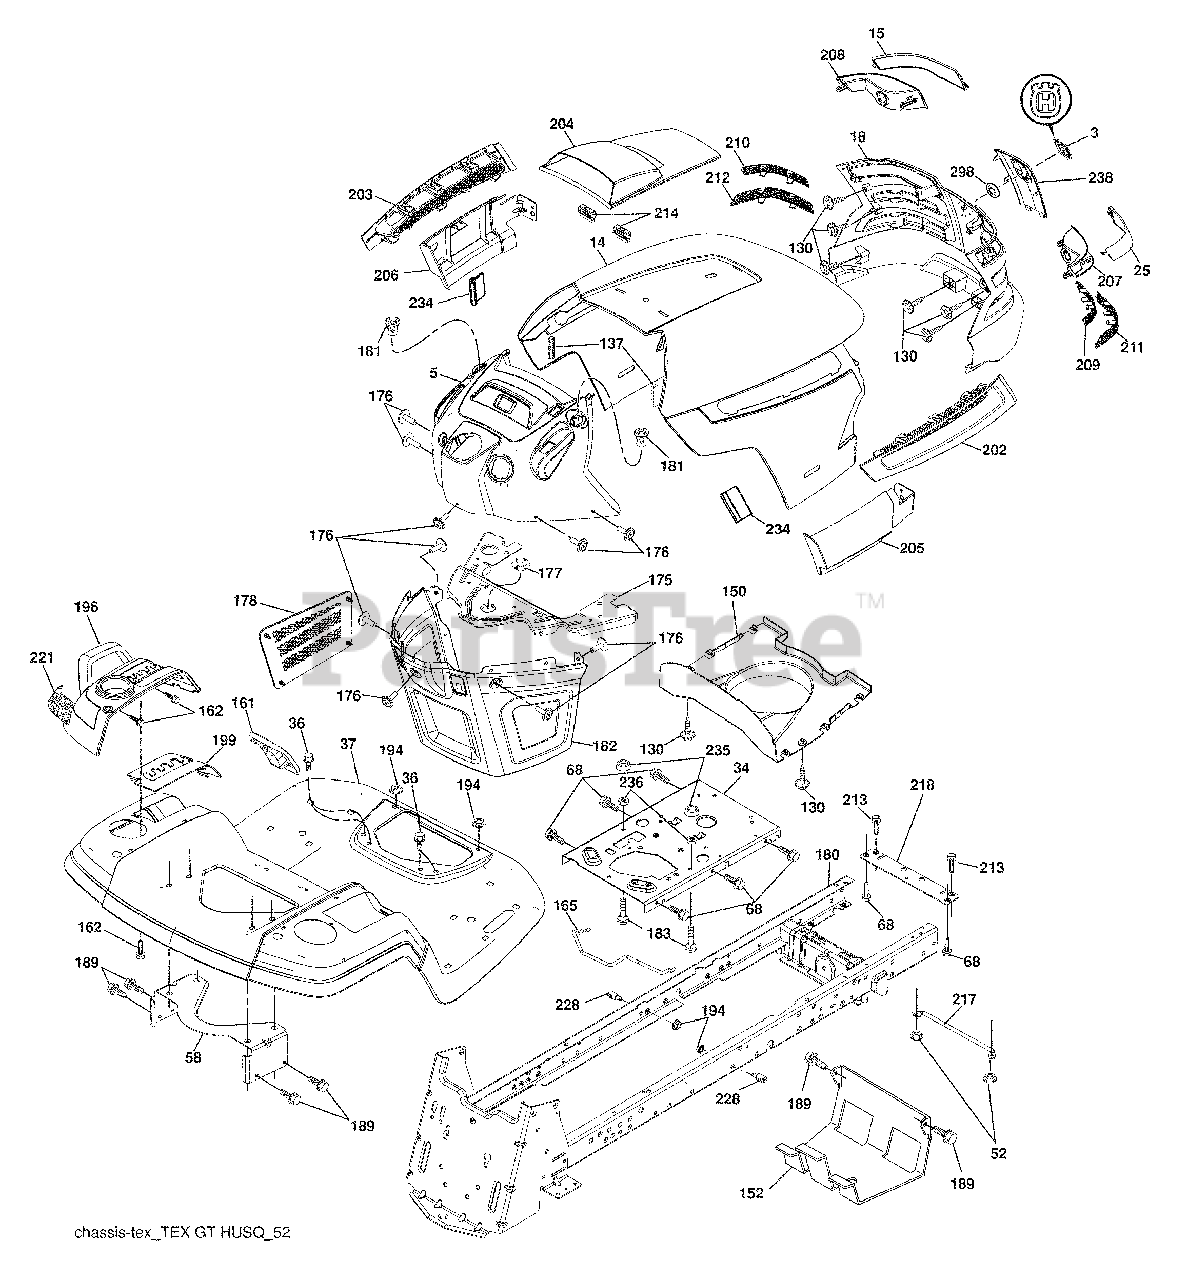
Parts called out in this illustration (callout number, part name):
3	Logo Husq.
14	Hood
34	Plate Engine
36	Screw 5/16-18 x 3/4
37	Fender
52	Nut Crown Lock 5/16-18
58	Bracket Fender
68	Screw 5/16-18 x 1/2
130	Screw #10 x 0.750 BOS Thread
137	Bumper Dash
150	Duct Heat Hood
152	Shield Browning/Debris
161	Console Fuel Window
162	Screw Hex Wsh Hi-Lo 1/4 x 1/2
165	Bracket Support Tank
175	Crossmember
176	Screw 10-24 x 5/8 Wshd Qdrx
177	Bushing Steering
178	Cargo Asm. Net
180	Chassis
181	Bushing Mtg. Fender Crgo.
182	Dash Lower
183	Bolt Fin Hex 5/16-18 unc x 1-1/4
189	Screw 5/16-18 x 3/4
194	Nut Lock Hex Flange 5/16-18
196	Console Asm. Deck Lift
199	Plate Deck Lift
202	Vent Side Hood RH
203	Vent Side Hood LH
204	Vent Asm Hood Top
205	Skirt Hood Side RH
206	Skirt Hood Side LH
209	Insert Hex Top RH
210	Insert Hex Top LH
211	Insert Hex Bottom RH
212	Insert Hex Bottom LH
213	Bolt Hex HD 5/16-18 unc x 3/4
214	Clip Retainer
221	Reflector LH
228	Stud Fastener
234	Bumper Hood
235	Spacer Fender
236	Nut Center Lock 5/16-18 unc
238	Trim Husq.
